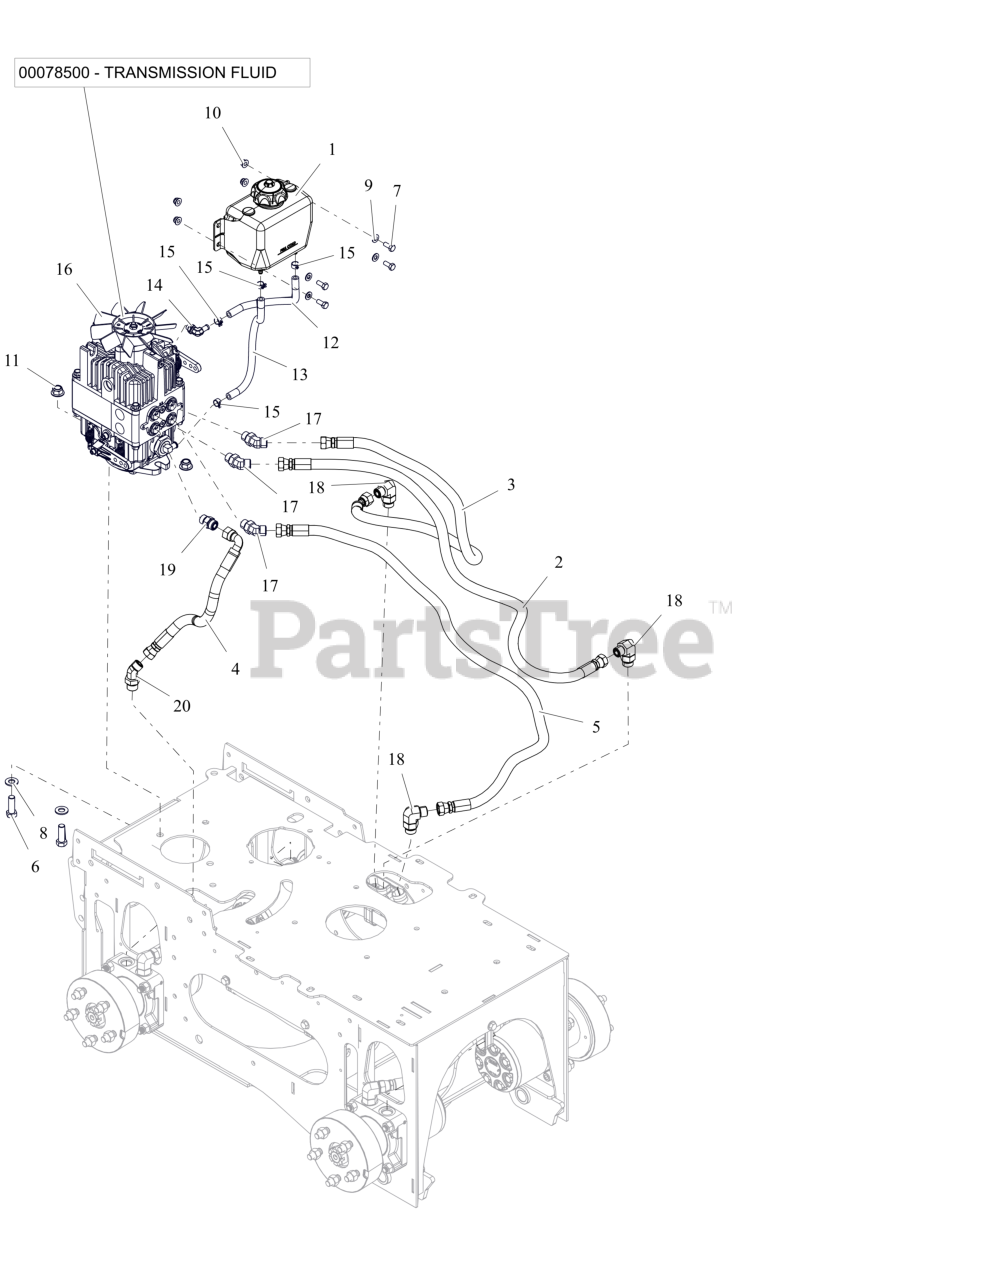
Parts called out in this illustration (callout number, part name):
1	TANK- OIL RESERVOIR
2	ASM-HOSE LF MTR A/B PORT
3	ASM- HOSE LR MTR B/PUMP A
4	ASM- HOSE PUMP B/RR MTR A LOW
5	ASM- HOSE RF MTR B/PUMP LOWER
6	BLT,HEX .50-13X1.50 G5 ZCC
7	BLT,HEX .31-18X.75 G5 ZCC
8	WSHR,FLT .531X1.062X.095 ZCC
9	WSHR,FLT .344X.688X.065 ZCC
10	NUT,LK-NYL-FLG .31-18 G5ZC120
11	NUT,NYL-FLG .50-13 GF ZCC
12	HOSE- OIL
13	HOSE- OIL
14	FITTING- HYD- SWIVEL ELBOW
15	CLAMP-HOSE 9/16"
16	PUMP- HYDRO
16	FLUID- MAMMOTH TRANSMISSION
17	FITTING- HYD ELB 45-8-8 V5OLO
18	FITTING- HYD ELB 90-10-8 C5OLO
19	FITTING- ADAPTOR 8-8 F5OLO-S
20	FITTING- HYD ELB 45-8-10 V5OLO
